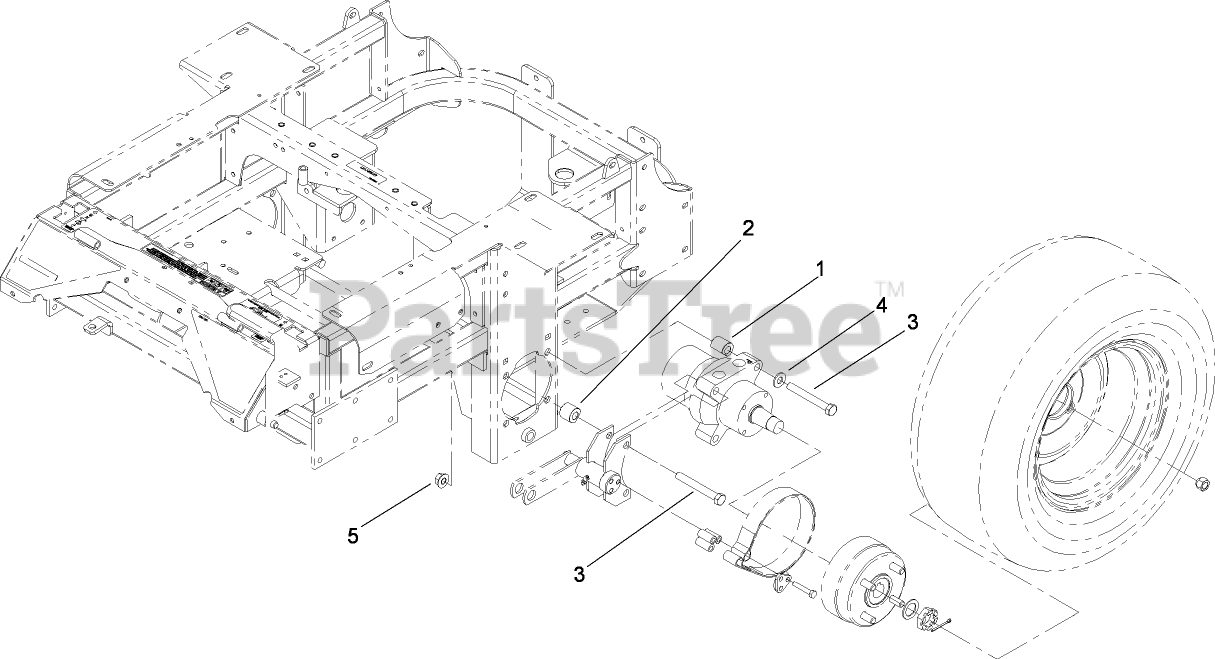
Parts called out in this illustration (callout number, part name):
1	SPACER-WHEEL, LONG
2	SPACER-WHEEL, SHORT
3	SCREW-HH
4	WASHER-THRUST
5	NUT-HHF
